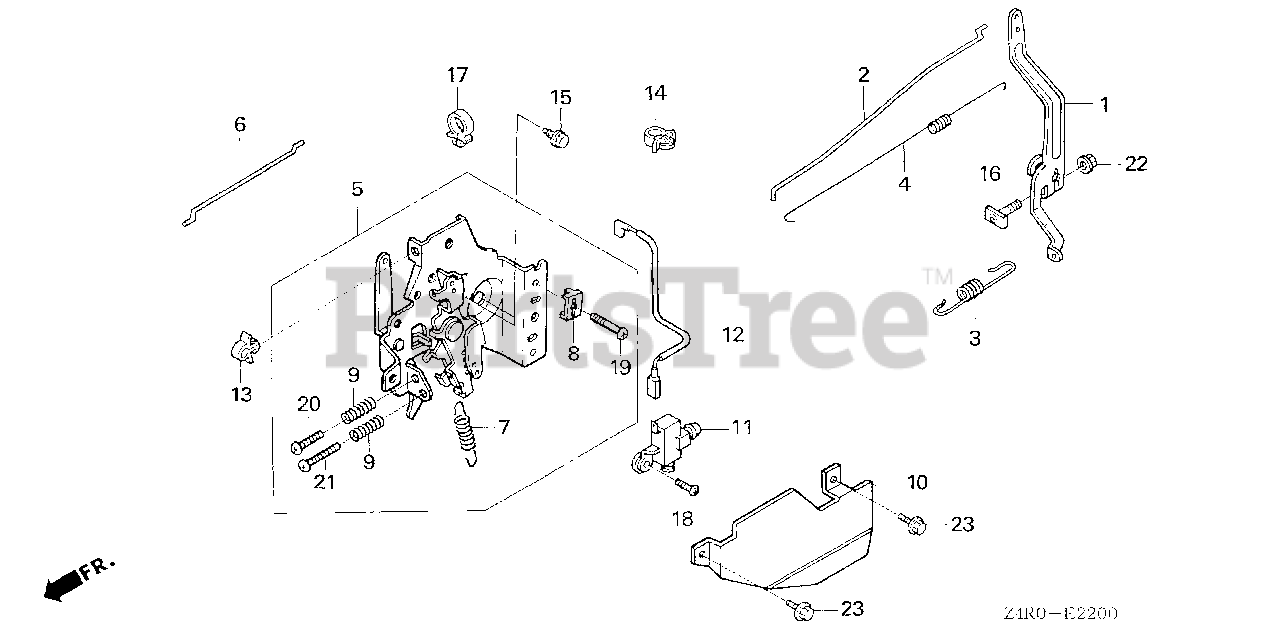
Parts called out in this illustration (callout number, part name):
1	ARM, GOVERNOR
2	ROD, GOVERNOR
3	SPRING, GOVERNOR
4	SPRING, THROTTLE RETURN
5	CONTROL ASSY.
6	ROD, CHOKE
7	SPRING, LEVER
8	HOLDER, CABLE
9	SPRING, CONTROL ADJUSTING
10	PROTECTOR, CONTROL
13	HOLDER, STOP SWITCH WIRE
13	HOLDER, WIRE (FASTEX)
14	CLAMP, BRAKE PIPE (GRAY)
15	BOLT, FLANGE (6X12) (CT200)
16	BOLT, GOVERNOR ARM
17	CLIP, WIRE HARNESS
19	SCREW, PAN (5X16)
20	SCREW, PAN (5X20)
21	SCREW, PAN (5X28)
22	NUT, FLANGE (6MM)
23	BOLT, FLANGE (6X10)
